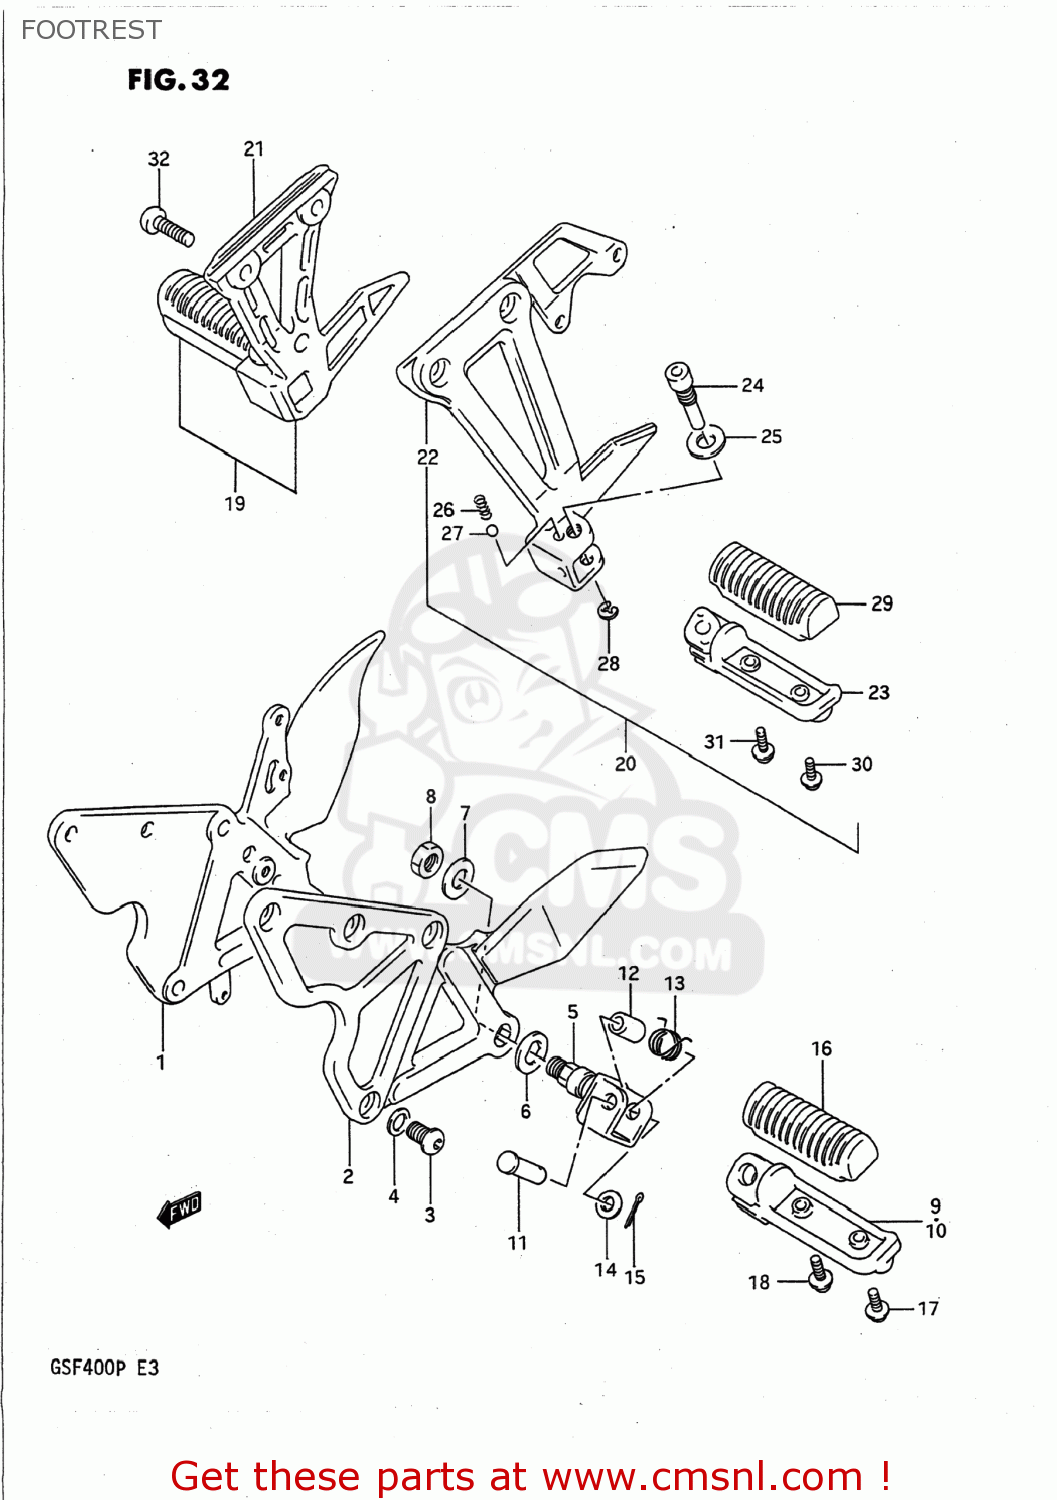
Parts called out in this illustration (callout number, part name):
1	BRACKET,FOOTREST,R
2	BRACKET,FOOTREST,L
3	BOLT
4	WASHER
5	BOSS,FR FOOTREST
6	PLATE,FOOTREST INNER
7	COTTER PIN
8	NUT, REAR AXLE
9	BAR,FOOTREST,R
10	BAR,FOOTREST,L
11	PIN
12	SPACER(8.1X12X22)
13	SPRING
14	WASHER(8.5X18X1)
15	PIN 20X15
16	RUBBER,FOOTREST
17	SCREW
18	SCREW
19	FOOTREST ASSY,PILLION,R
20	FOOTREST ASSY,PILLION,L
21	BRACKET
22	BRACKET
23	BAR,PILLION FOOTREST,R
24	BOLT,PILLION FOOTREST
25	WASHER
26	SPRING
27	BALL
28	E RING
29	RUBBER,FOOTREST
30	SCREW
31	SCREW
32	BOLT
33	BOLT(8X35)
